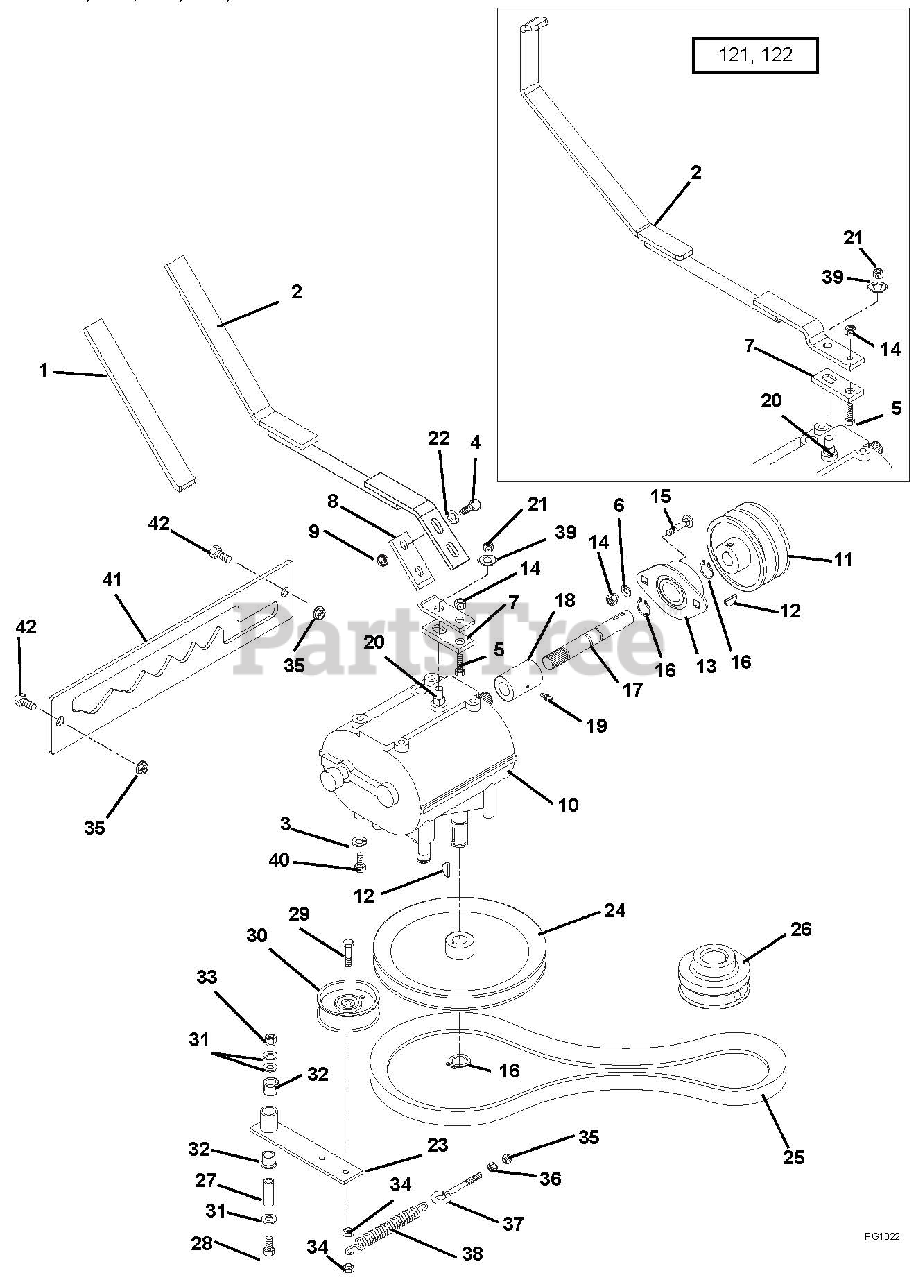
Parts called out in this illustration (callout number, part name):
1	Grip
2	Lever, Shift
3	Washer-Locking .31 x .078 Regular
4	Bolt-Hex .31-18 x 1.00 Grade 5
5	Bolt-Hex .25-20 x 1.00 Grade 5
6	Washer-Flat-Steel .25 x .562 x .049
7	Plate, Shift
8	Arm, Shift
9	Nut-Locking-Top-Flange .31-18
10	Transmission
11	Sheave, Drive
12	Key-Woodruff .19 x .75
13	Bearing-Flange .625 x 1.875 x .797
14	Nut-Locking-Nylon .25-20
15	Bolt-Round Head Square Neck .25-20 x .75 Grade 5
16	Ring-Retaining-External .579 x .930
17	Shaft, Half
19	Fitting, Lube, .25-28
20	Switch-Neutral Start N.C.
21	Nut-Locking-Center .38-24
22	Washer-Flat-Steel .344 x .688 x .065
23	Weldment, Ground Drive Idler
24	Pulley-V 7.50 x .63 Sheave Transmission
24	Pulley-V 7.50 x .626
25	V-Belt 4L-Section 33.9
26	Sheave, Clutch
27	Bushing, Steel .56 x .745 x 2.04
28	Bolt-Hex .50-13 x 3.25 Grade 5
29	Bolt-Hex .38-16 x 2.00 Grade 5
30	Idler-Pulley Flat 3.25 x .625
31	Washer-Flat-Steel .531 x 1.06 x .095
32	Bushing-Flange Nylon .762 x 1.00 x .58 x 1.48
33	Nut-Locking-Nylon .50-13
34	Nut-Locking-Jam-Center .375-16
35	Nut-Locking-Nylon .38-16
36	Nut-Hex .38-16
37	Eye Bolt
38	Spring, Extension
39	Washer, Locking .38 x .13
40	Bolt-Hex .31-18 x .75 Grade 5
41	Plate, Shift Lever Detent
42	Bolt-Hex .38-10 x 1.00 Grade 5
